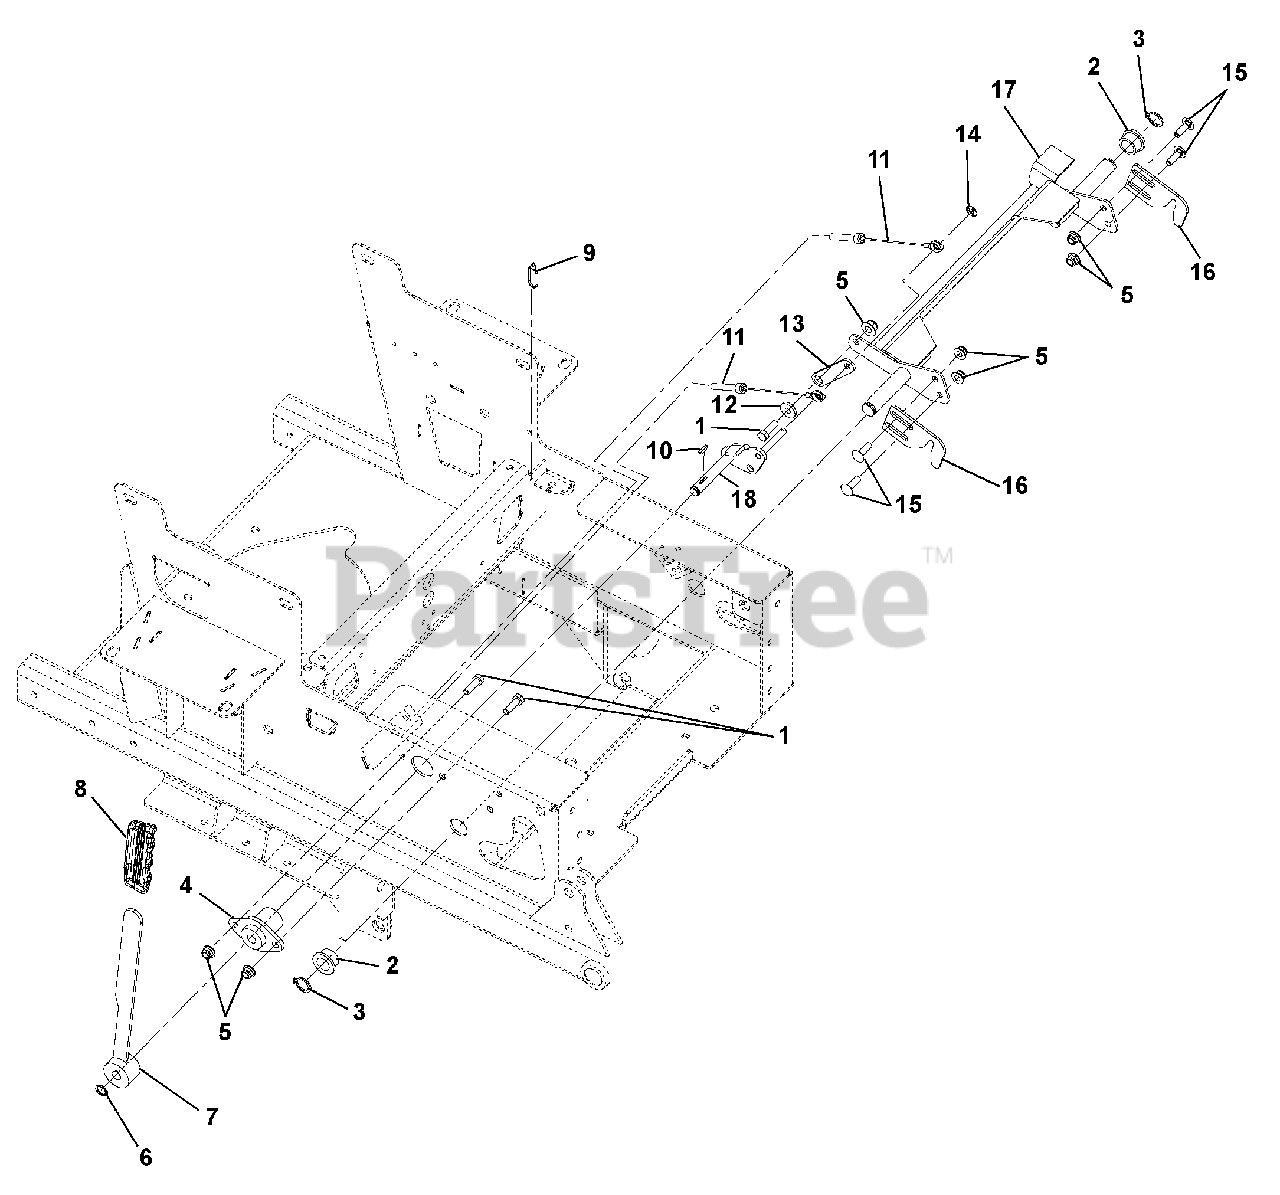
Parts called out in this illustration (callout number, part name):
1	BLT-HEX .31-18X1.00 GR5 YWZC
2	BSHG-FLG .750X1.000X.625X1.250
3	RG-RTNG-EXT .689X.078
4	BUSHING, FLANGED
5	NUT-LK-NYL-FLG .31-18 YWZC
6	RG-RTNG-EXT .500X.050 (SNAP)
7	WMT - PARKING BRAKE ARM
8	GRIP, PARKING BRAKE (YELLOW)
9	CABLE TIE LG 5-1/2
10	KEY-WDRF .13X.63 HRD#5
11	CABLE, BRAKE ACTUATING
12	BSHG, FLG .325X.499X.26X.88
13	PLATE, NEUTRAL INTERLOCK
14	NUT-PUSH .312
15	BLT-RDHDSQNK .31-18X1.00 G5YZ
16	NEUTRAL LOCK LATCH - BLACK
17	WMT, PT100 NEUTRAL LOCK
18	WMT, PARK BRAKE ARM
